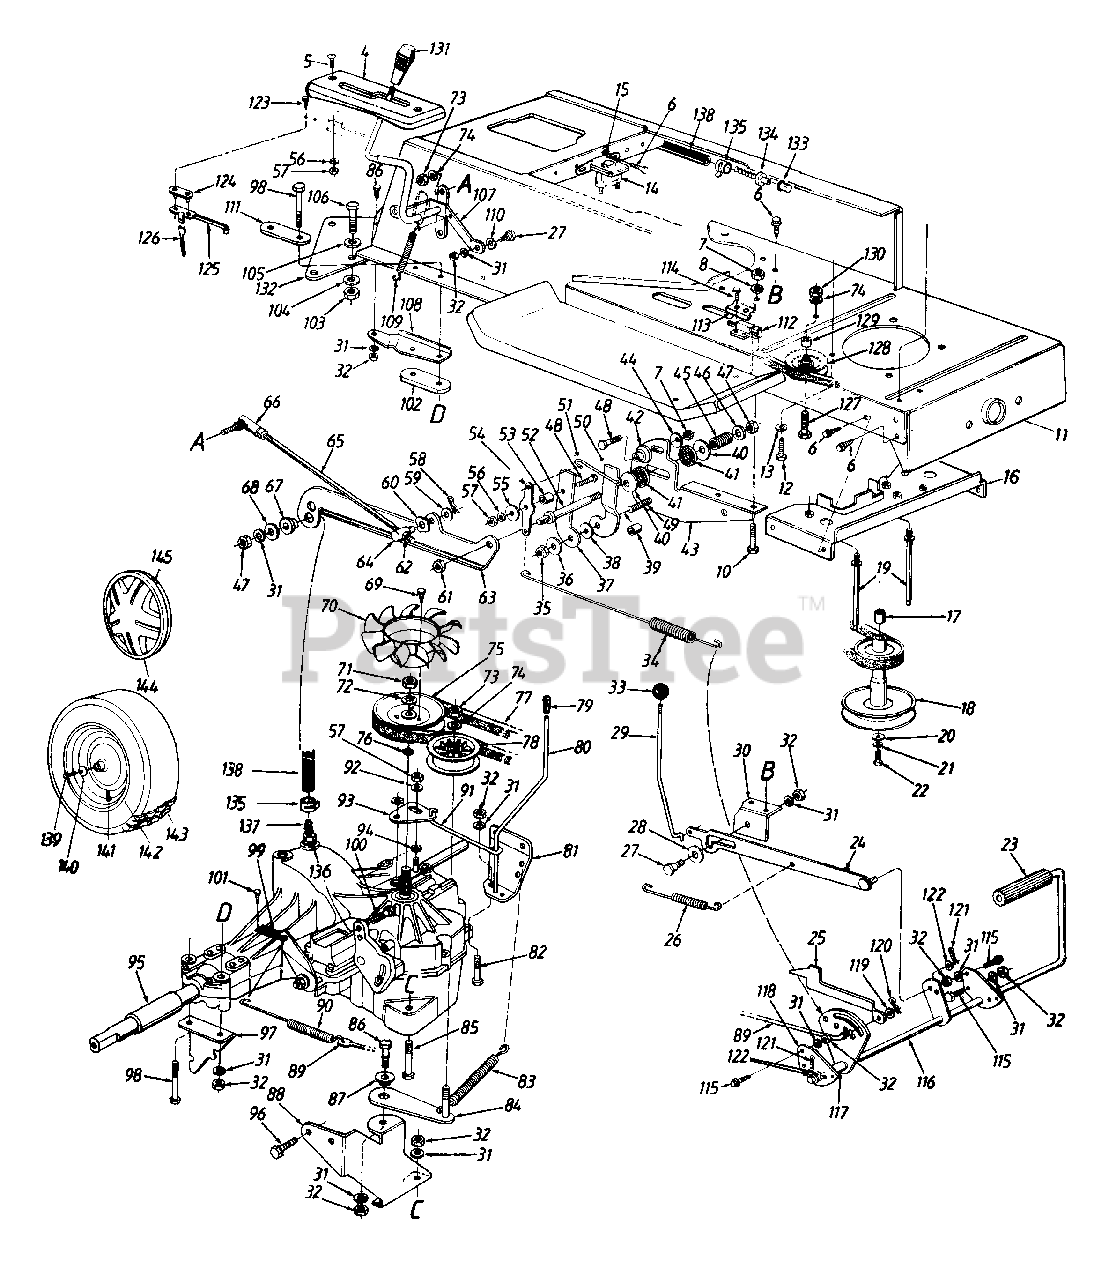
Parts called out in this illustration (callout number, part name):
4	Index Bracket
5	Pan Hd. Mach. Scr. 1/4-20 x .75" Lg.
6	Hex Wash. Hd. TT-Tap Scr. 1/4-20 x .5" Lg.
7	Hex Nut 1/4-28 Thd.
8	L-Wash. 1/4" I.D.
10	Hex . Bolt 1/4-28 x .62" Lg.
13	Fl-Wash. .406" I.D. x 1.25"
14	Solenoid
15	Ext. L-Wash. 1/4" I.D.
18	Engine Pulley
19	Belt Guard Stud 3.6" Lg.
20	Fl-Wash. 7/16" I.D. x 1.25" O.D.
21	L-Wash. 7/16" I.D.
22	Hex Bolt 7/16-20 x 1.5" Lg.
23	Foot Pad
26	Foot Pedal Return Spring
27	Shld. Bolt .437" Dia. x .268"
28	Fl-Wash. 7/16" I.D. x 1-3/8" O.D.
29	Lock-up Rod
30	Bracket
31	L-Wash. 5/16" I.D.
32	Hex Nut 5/16-18 Thd.
33	Ball Knob
34	Neutral Return Spring
35	Hex Nut 5/16-24 Thd.
36	Fl-Wash. .344" I.D. x 1" O.D.
37	Scissor - Flat
38	Fl-Wash. .33" I.D. x 1.25" O.D.
39	Spacer
40	Bell-Wash. .4" I.D. x 1.13" O.D.
41	Friction Washer
42	Centering Gauge Spacer
44	Bell-Wash. .265" I.D. x .75" O.D.
45	Comp. Spring 1.19" Lg.
46	Fl-Wash. .312" I.D. x .75" O.D.
47	Hex Nut 5/16-24 Thd.
48	Hex Bolt 1/4-28 x 1" Lg. (Gr. 5)
49	Rib Neck Bolt 5/16-24 x .84" Lg.
50	Scissor-Offset
51	Neutral Return Rod
52	Friction Disc Stud
53	Shld. Spacer
54	Neutral Return Lever
55	Fl-Wash. .265" I.D. x 1" O.D.
56	L-Wash. 1/4" I.D.
57	Hex Nut 1/4-20 Thd.
58	Hairpin Clip
59	Fl-Wash. .375" I.D. x .87" O.D.
60	Spring Wash. .39" I.D.
61	Hex L-Nut 3/8-24 Thd.
62	Hex Jam Nut 3/8-24 Thd.
63	Neutral Return Brkt.
64	Ferrule 3/8-24 Thd.
65	Control Rod
66	Ball Joint 3/8-24 Thd.
67	Shld. Spacer .5" Dia. x .27" Lg.
68	Fl-Wash. .349" I.D. x .879" O.D.
69	Hex Wash. Hd. Tap Scr. #12 x 3/8" Lg.
70	Fan
71	Hex Nut 1/2-20 Thd.
72	L-Wash. 1/2" I.D.
73	Hex Nut 3/8-24 Thd.
74	L-Wash. 3/8" I.D.
75	Transmission Pulley
76	Wire Ring
77	"V"-Belt
78	Fl-Idler Pulley 2.75" O.D.
79	Rod End Grip
80	Bypass Control Lever
83	Ext. Spring 6.12
86	Hex Bolt 5/16-18 x .75" Lg.
87	Shld. Spacer .5" Dia. x .27" Lg.
90	Ext. Spring
91	Bypass Actuator Rod
92	Fl-Wash. .281" I.D. x .5" O.D.
93	Bypass Adjustment Brkt.
94	External L-Wash. 1/4" I.D.
95	Sleeve .758" I.D. x 1" O.D.
96	Hex . Wash. TT-tap Scr. 5/16-18 x .62" Lg.
99	Tension Spring
100	Hex Bolt 5/16-24 x 1" Lg. (Special)
101	Hex Wash. Hd. AB-Tap Scr. #10 x .5" Lg.
102	Transaxle Spacer
103	Hex Nut 7/16-14 Thd. (Gr. 5)
104	Fl-Wash. .469" I.D. x .875" O.D.
105	Bell-Wash. .46" I.D. x 1.13" O.D.
106	Hex Bolt 7/16-14 x 1" Lg.
107	Speed Control Lever Ass'y.
110	Spr-Wash. .445" I.D. x .75" O.D.
112	Safety Switch (Clutch)
113	Switch Plate
114	Truss Mach. B-Tap Scr. #10 x .5" Lg.
115	Hex Wash. TT-Tap Scr. 5/16-18 x .75" Lg.
120	Cotter Pin 3/32" Dia.
121	Cotter Pin 1/8" Dia.
122	Fl-Wash. .64" I.D. x .94" O.D.
123	Hex Wash. Hd. AB-Tap Scr. #8 x .5" Lg.
124	Insulator Nut Plate
125	Reverse Safety Switch
126	Extension Wire
127	Hex Bolt 3/8-16 x 1.5" Lg.
128	Idler Pulley
129	Fl-Wash. .39" I.D.
130	Hex Nut 3/8-16 Thd.
131	Shift Knob
132	Hitch Plate Extension
133	Vent Cap
134	Plastic Vent
135	Clamp
136	"O"-Ring
137	Hose Fitting
138	Fuel Line 18" Lg.
139	Hex Bolt 5/16-24 x .75" Lg.
140	Bell-Wash. .345" I.D. x .88" O.D.
141	Air Valve
142	Rim Only
143	Wheel Ass'y. Comp.
144	Hub Cap Gray
145	Spring Clip
